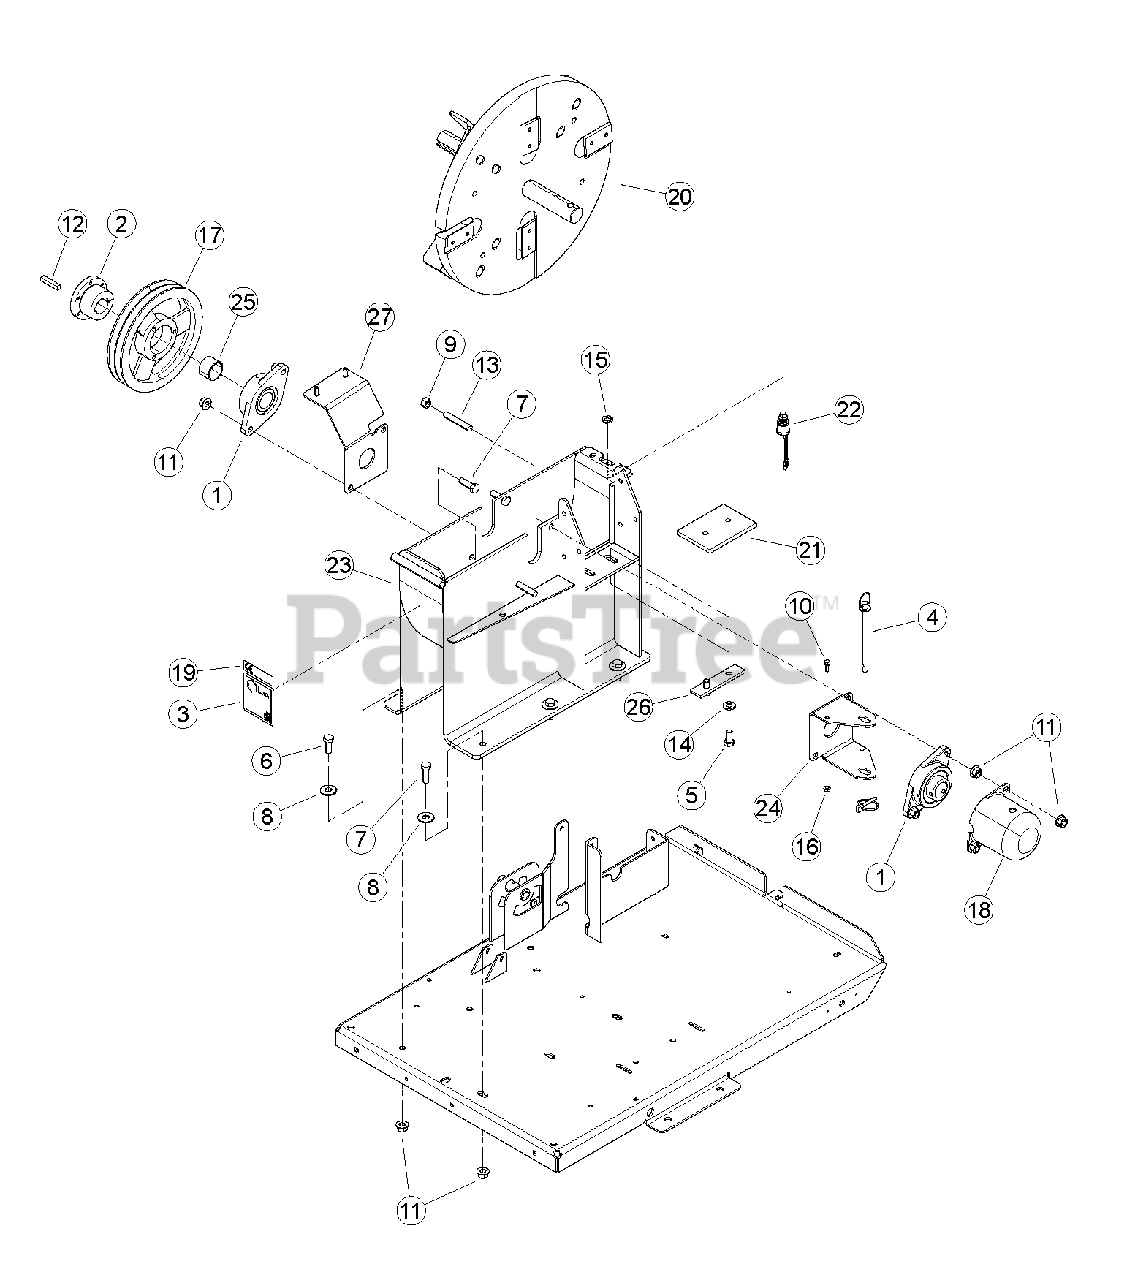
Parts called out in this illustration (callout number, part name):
1	BEARING, 1-1/2" 2-BOLT SET SCREW
2	BUSHING, SK 1-1/2"
3	DECAL, 109 DB (CE COMPLIANT ONLY)
4	PIN, HITCH 1/2 X 6-1/2 W/ LYNCH
5	BOLT, 1/2 X 1 GR5 HEX CAPSCREW ZP
6	BOLT, 1/2 X 1-1/4" GR5 HHCS NC ZP
7	BOLT, 1/2-13 X 1-1/2 HEX HD GR5
8	WASHER, 1/2 FLAT
9	NUT, 1/2-13 GR5 CENTERLOCK GRB
10	BOLT, 1/4-20 X 3/4 FLANGE GR5 CZP
11	NUT, 1/2-13 NYLOCK FLANGE
12	KEY, 3/8" SQ X 2" LG PLAIN
13	STUD, 1/2"-13 X 3"LG B7 ZP
14	WASHER, 1/2 HI-STRENGTH SAE ZP
15	NUT, 5/8-32 JAM
16	NUT, 1/4-20 NYLOCK FLANGE
17	SHEAVE, 2B9.4 SK
18	CAP, LARGE SHAFT
19	DECAL, CH5627 INFORMATION (CE COMPLIANT ONLY)
20	ASSEMBLY, 5" ROTOR
21	ANVIL, 4 INCH CHIPPER
22	ASSEMBLY, SEALED SWITCH
23	WELDMENT, CHIPPER BOTTOM
24	BRACKET, ROTOR LOCK
25	TUBE, 1.75 OD X .109 WALL X 1.150
26	STRIP, ADJUSTOR BLOCK
27	WELDMENT, BELT GUARD SUPPORT
